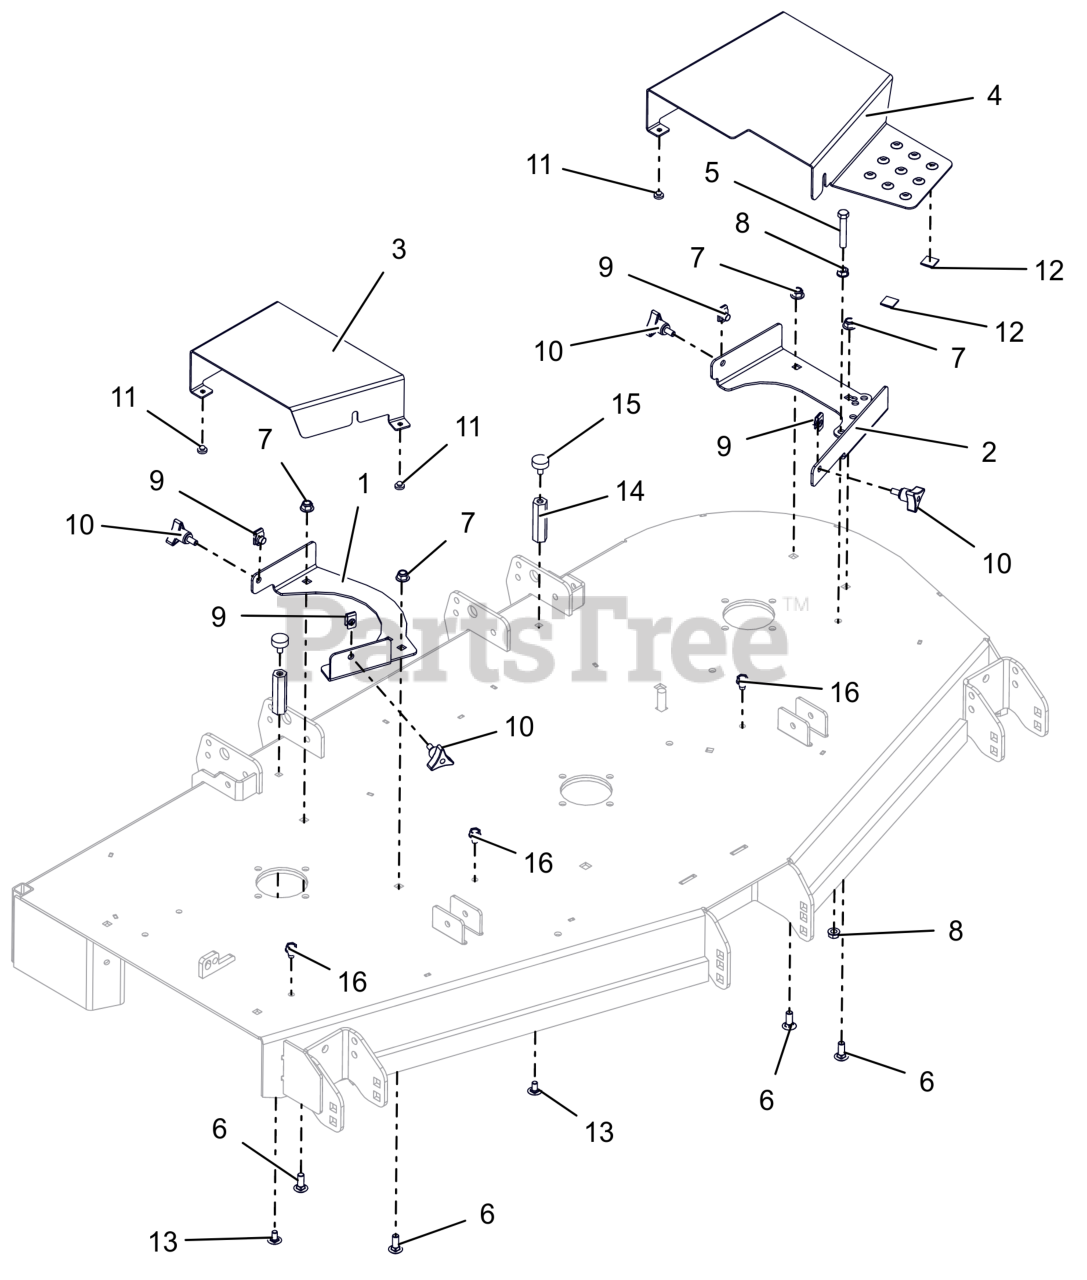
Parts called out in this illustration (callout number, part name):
1	BRKT, RH BELT GUARD MTG - RED
2	BRKT, LH BELT GUARD MTG - RED
3	PT148-152 DECK RH BELT GRD-RED
4	PT100 DECK LH BELT GUARD - RED
5	BLT,HEX .38-16X2.25 G5 ZCC
6	BLT, RHSN .38-16X1.00 G5 ZCC
7	NUT,NYL-FLG .38-16 GF ZCC
8	NUT, SPNLK-FLG .38-16 G5 ZCC
9	NUT-CLIP RETAINER 5/16-18X.56
10	KNOB,WING STUD 5/16-18 X .75
11	BUMPER GROMMET
13	BLT, RHSSN .31-18X.625 G5 ZCC
14	NUT, COUPLING .31-18 2.75 LG
15	BUMPER, RUBBER
16	SCR,TAP .375-16X.50 HWH TR ZCC
